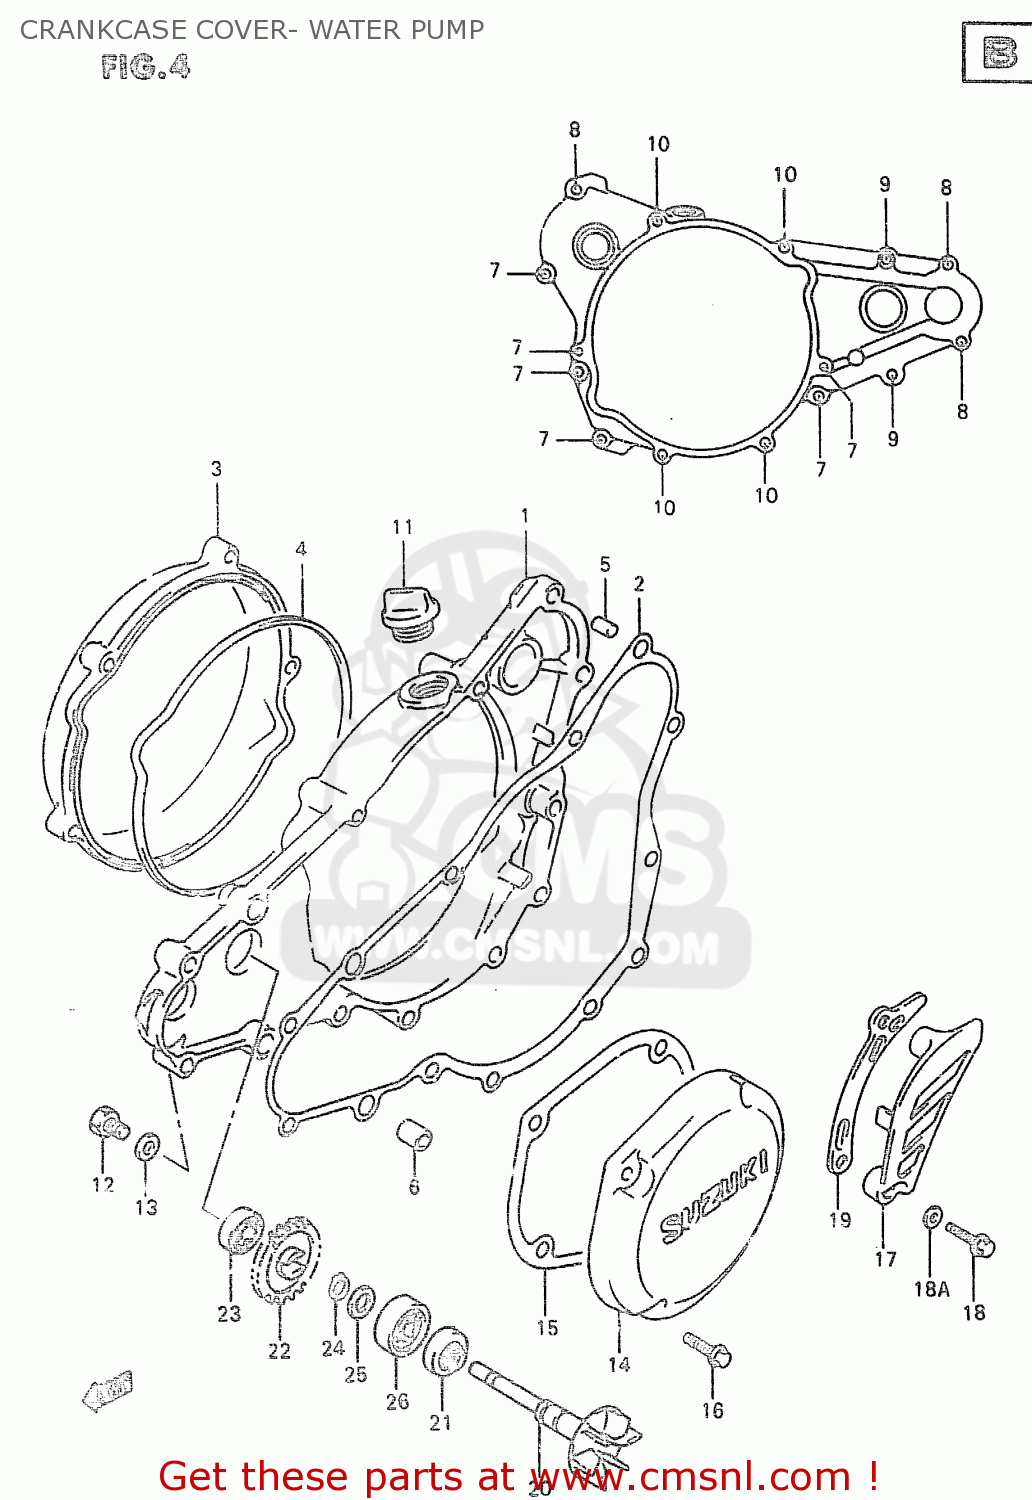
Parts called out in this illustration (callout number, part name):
1	COVER,CLUTCH
2	GASKET,CLUTCH COVER
3	COVER,CLUTCH,OUTER
4	O RING,CL COVER OUTER
5	PIN
6	PIN
7	SCREW
8	BOLT,G/S SWITC
9	BOLT
10	BOLT
11	PLUG SET
12	SCREW(6X10)
13	GASKET(6.2X11X1).2 (NAS)
14	COVER,MAGNETO
15	GASKET,MAGNETO COVER
16	SCREW
17	COVER,ENGINE SPROCKET
18	SCREW
18A	WASHER(6.5X14X2)
19	PLATE,FR CHAIN GUIDE
20	IMPELLER,WATER PUMP
21	SEAL,WATER PUMP OIL
22	GEAR,WATER PUMP DRIVEN
23	BEARING(8X22X7)
24	CIRCLIP,10MM
25	WASHER,THRUST
26	BEARING(10X26X8)
